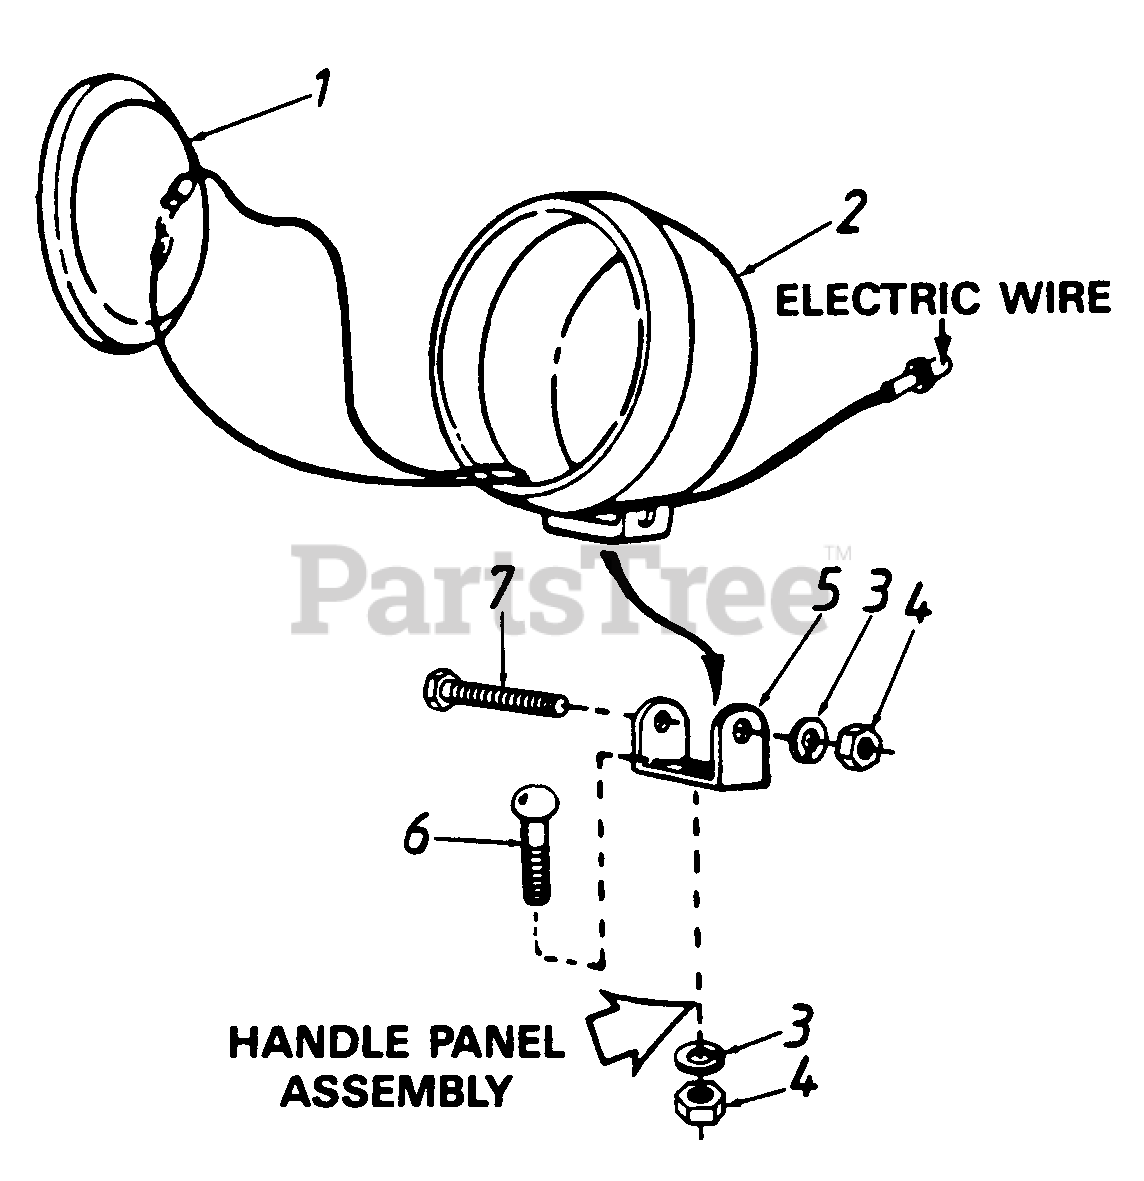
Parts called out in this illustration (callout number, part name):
1	Sealed Beam Headlight
2	Lamp Assembly
3	L.-Wash. 5/16" I.D.
4	Hex Nut 5/16-18 Thd.*
5	Lamp Mounting Bracket
6	Carriage Bolt 5/16-18 x 1/4
7	Hex Bolt 5/16-18 x 2" Lg.
